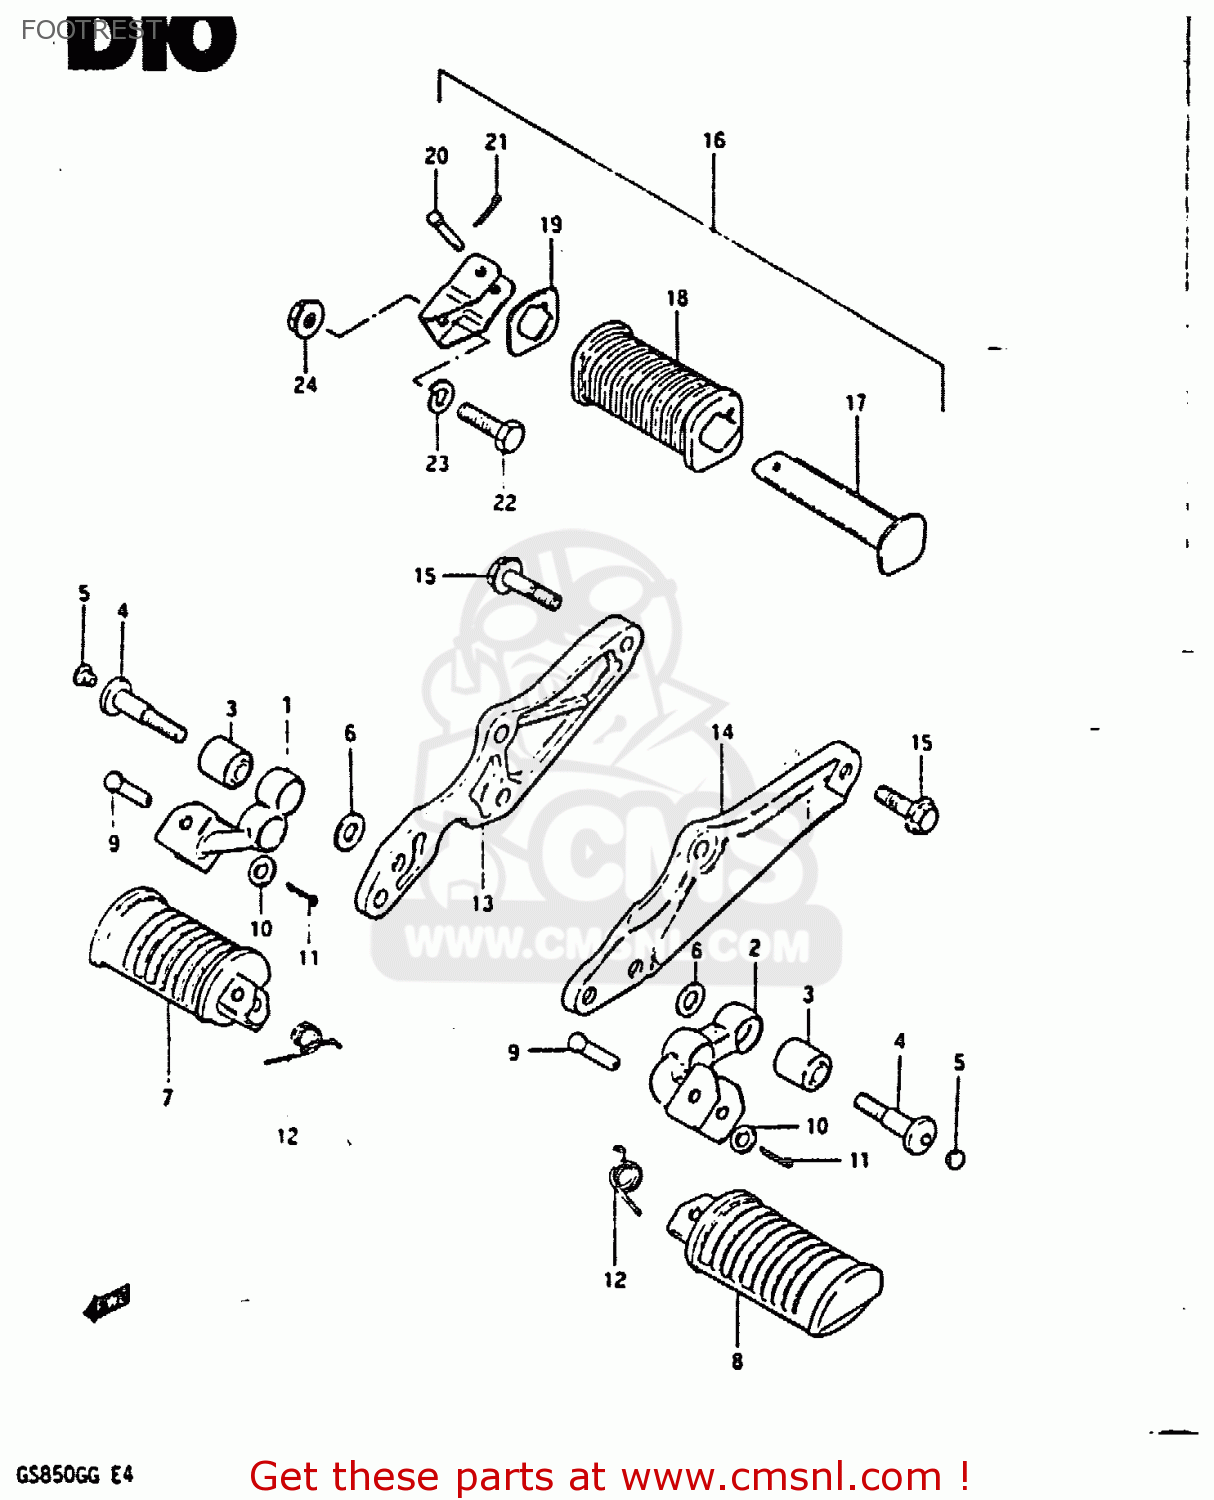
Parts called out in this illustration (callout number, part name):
1	BAR,FRONT FOOTREST,RIGHT
2	BAR,FRONT FOOTREST,LEFT
3	BUSH
4	BOLT(10X50)
5	CAP
6	WASHER(10.5X20X3.2)
7	RUBBER,PILLION FOOTREST,R
8	RUBBER,PILLION FOOTREST,L
9	PIN
10	WASHER
11	PIN 20X20
12	SPRING
13	BRACKET,MUFFLER,RIGHT
14	BRACKET,MUFFLER,LEFT
15	BOLT
16	FOOTREST ASSEMBLY,REAR
17	BAR,REAR FOOTREST
18	RUBBER,RR FOOTREST
19	WASHER,RR FOOTREST RUBBER
20	PIN
21	PIN 20X20
22	BOLT,M10X1.25X
23	LOCK WASHER
24	NUT
